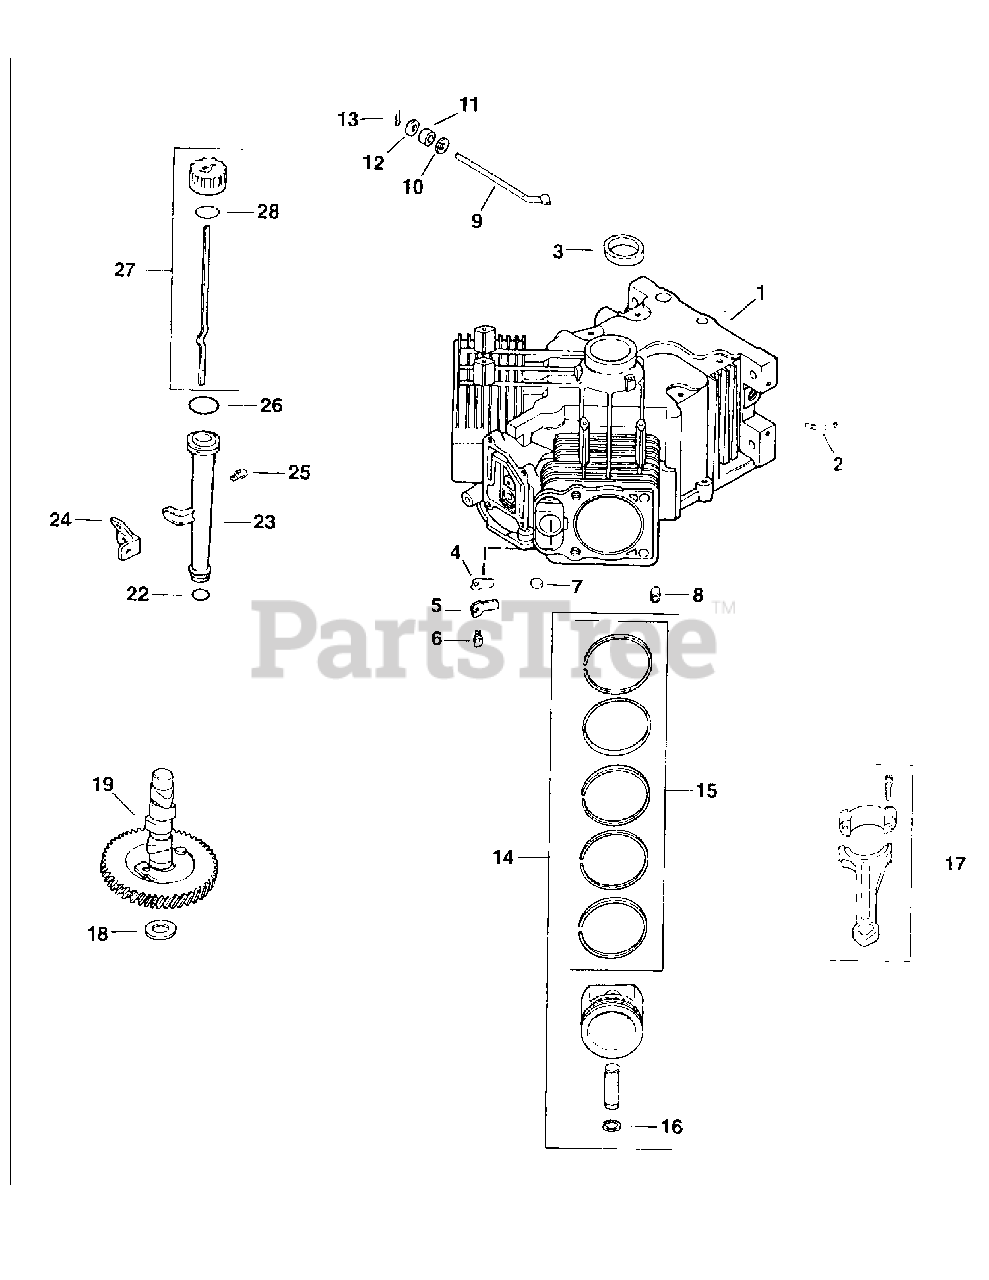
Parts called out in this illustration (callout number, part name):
1	Crankcase
3	Seal, Oil
4	Reed, Breather
5	Retainer, Reed
6	Screw, Hex Flange
7	Plug, Cup
8	Pin, Dowel Locating
9	Shaft, Governor Cross
10	Washer, Plain 1/4"
11	Seal, Governor Cross Shaft
12	Washer, Plain 6mm
13	Pin, Hitch
14	Piston w/Ring Set (Std.)
14	Piston w/Ring Set (.25)
14	Piston w/Ring Set (.50)
15	Ring Set (Std.)
15	Ring Set (.25)
15	Ring Set (.50)
16	Retainer, Piston Pin
17	Connecting Rod (Std.)
17	Connecting Rod (.25)
18	Shim, Camshaft (A.R.) (White)
18	Shim, Camshaft (A.R.) (Blue)
18	Shim, Camshaft (A.R.) (Red)
18	Shim, Camshaft (A.R.) (Yellow)
18	Shim, Camshaft (A.R.) (Green)
18	Shim, Camshaft (A.R.) (Gray)
18	Shim, Camshaft (A.R.) (Black)
19	Camshaft
23	Tube, Oil Fill
24	Bracket, Oil Fill Tube
25	Screw, Hex Flange
27	Dipstick Assembly
